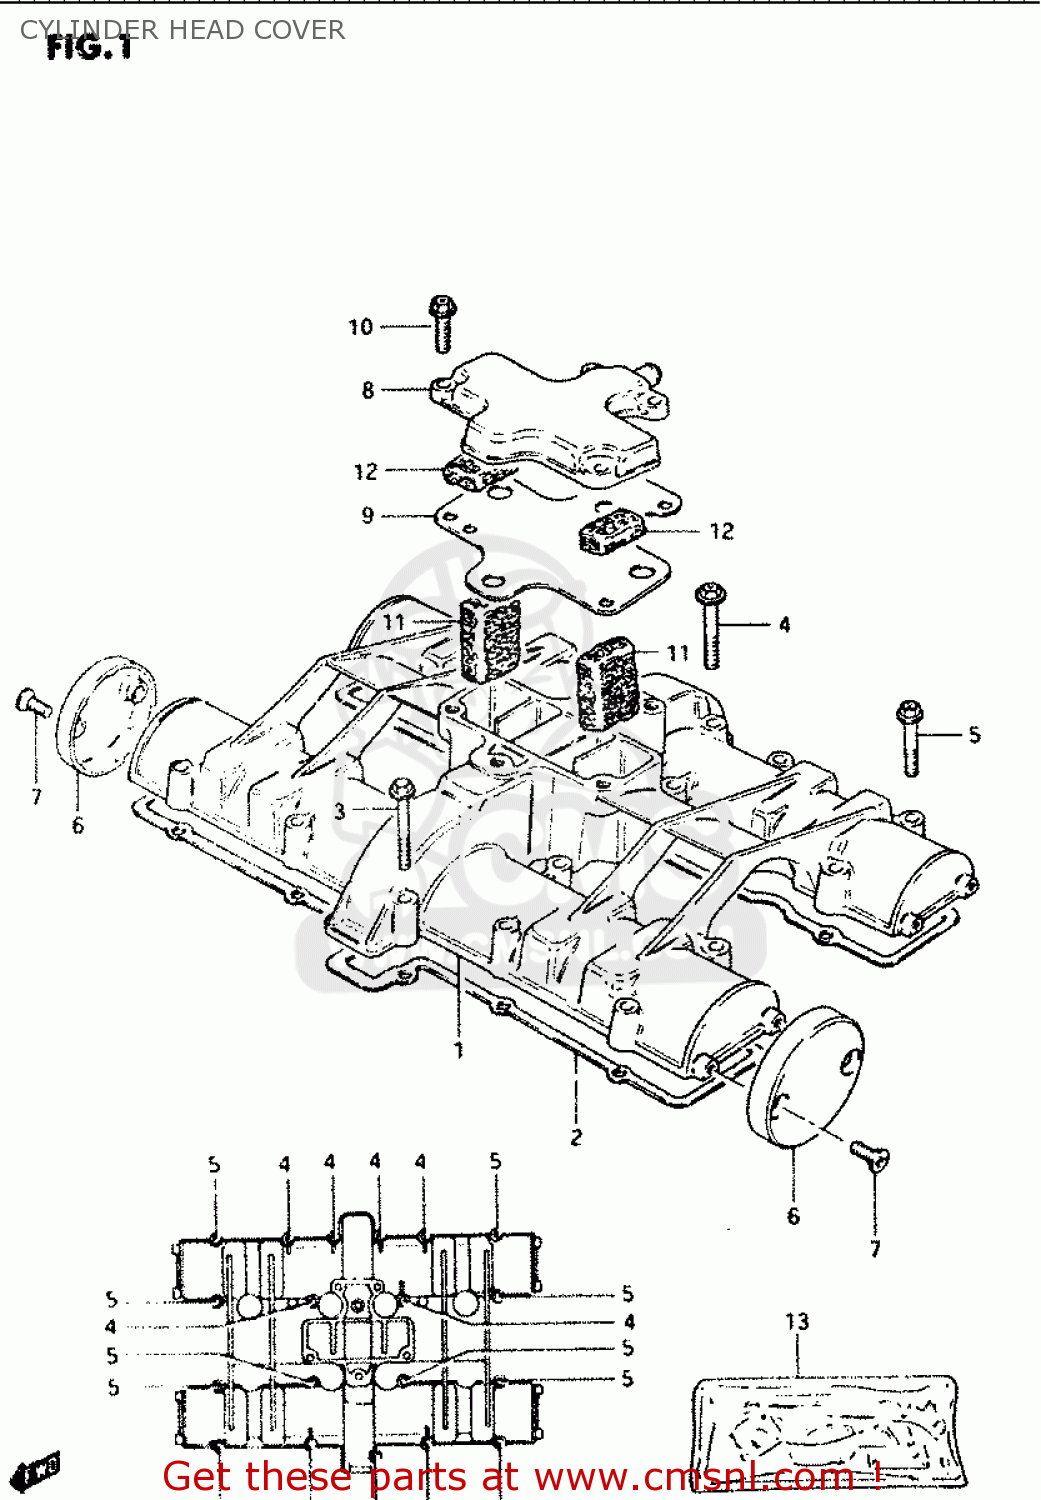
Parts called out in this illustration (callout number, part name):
1	COVER,CYLINDER HEAD
2	GASKET,CYLINDER HEAD COVER (MCA)
3	BOLT (6X45)
4	BOLT
5	BOLT 6X35
6	CAP,CYLINDER HEAD COVER
7	SCREW(5X12)
8	COVER,BREATHER
9	GASKET (MCA)
10	BOLT
11	COVER,BREATHER
12	SEPARATOR,OIL BREATHER
13	GASKET SET
